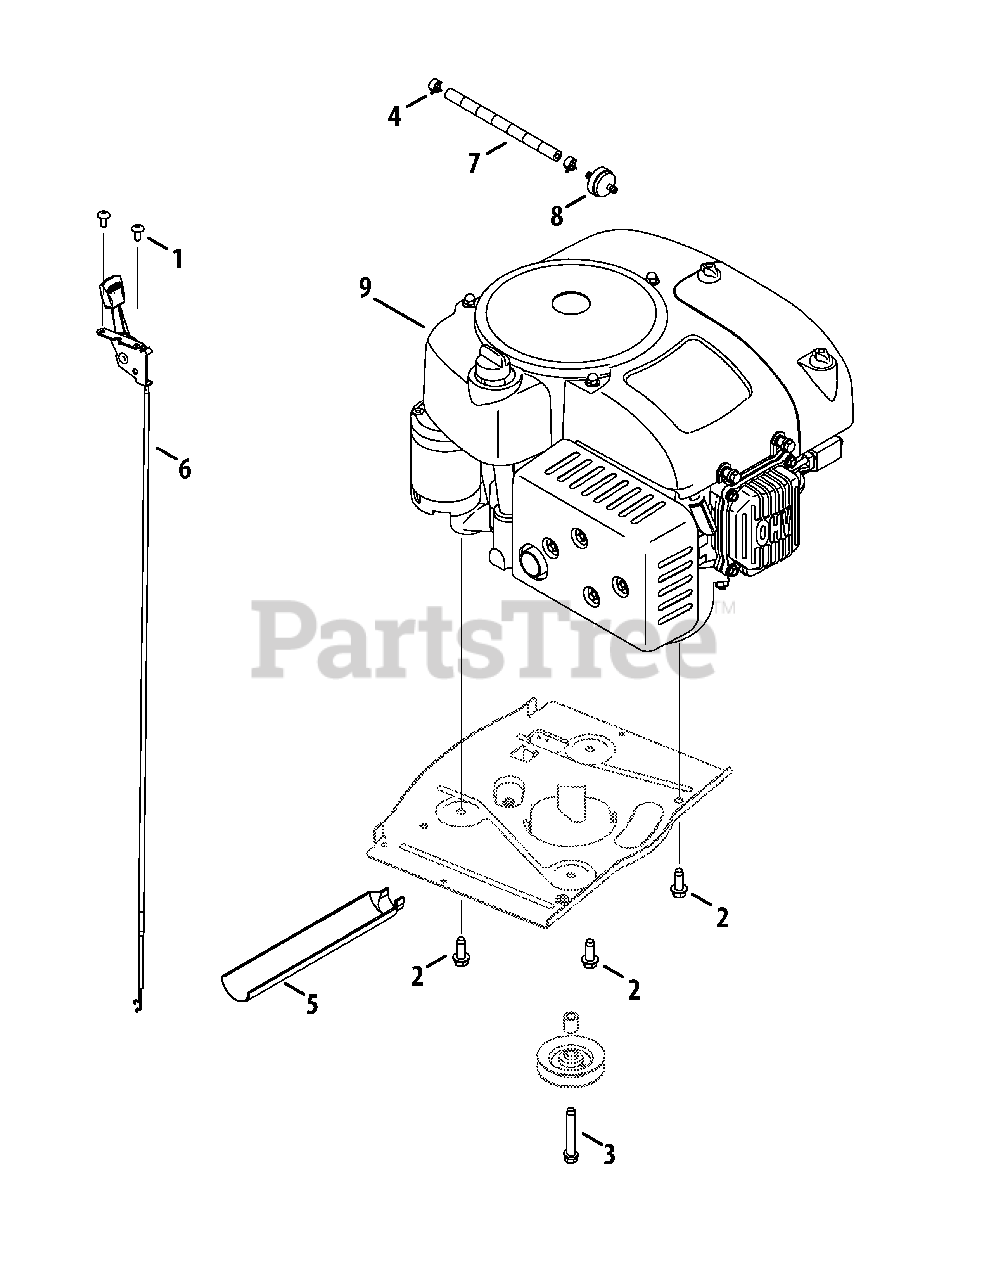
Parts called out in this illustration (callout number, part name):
1	Tap Screw, 1/4-20x0.500
2	Tap Screw, 3/8-16x1.000
3	Tap Screw, 3/8-16x2.250
4	Hose Clamp, .490 DIA.
5	Oil Drain Sleeve
6	Throttle/Choke Cable 31 Lg.
7	Low Permeation Fuel Line, 1/4
8	Fuel Filter
